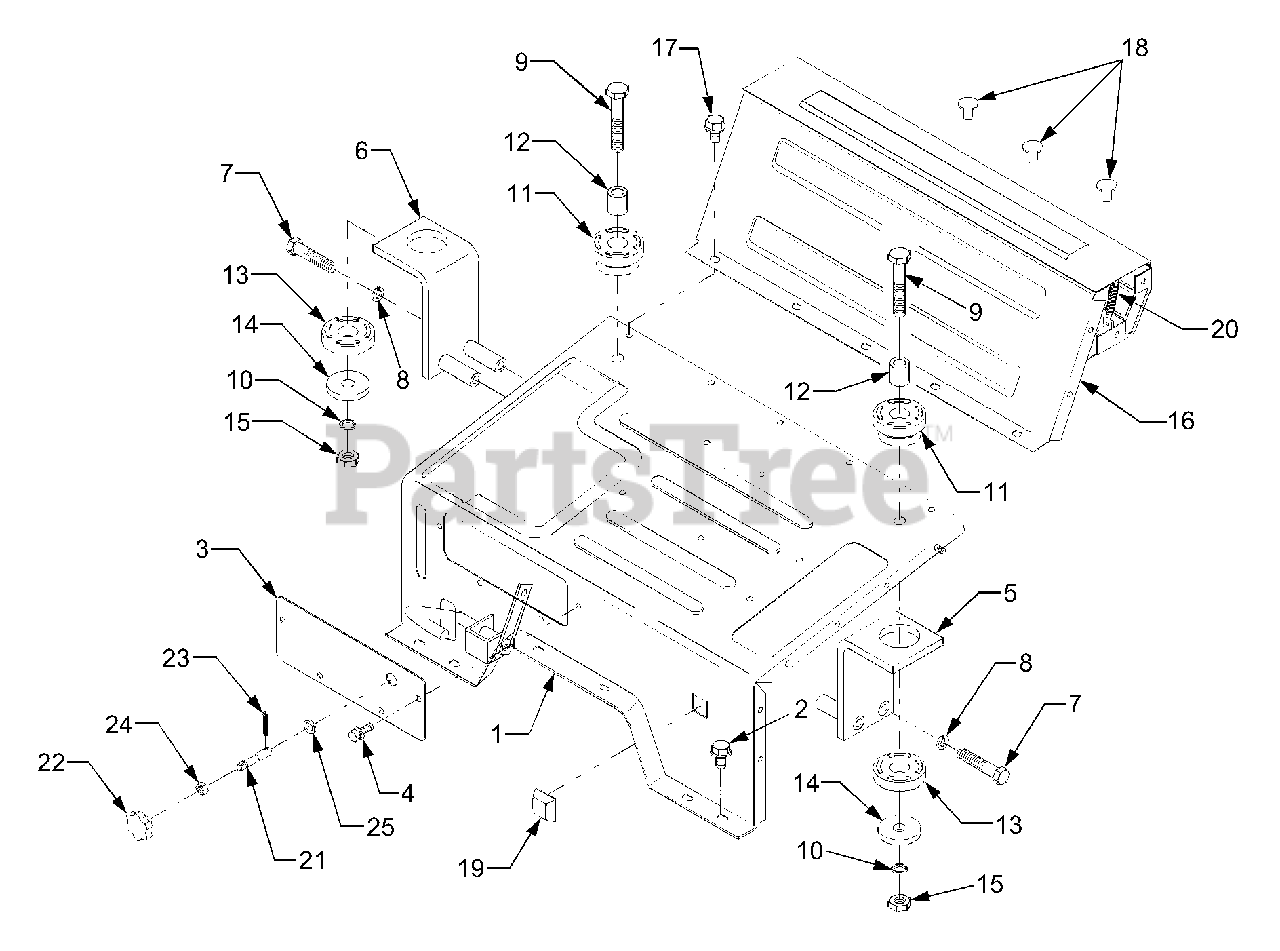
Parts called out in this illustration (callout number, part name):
1	Seat Floor Ass'y
5	Support, Seat Floor (LH)
6	Support, Seat Floor (RH)
8	Washer, Spring
10	Washer, Spring
11	Rubber, Cabin Cushion (A)
12	Collar, Cabin Cushion (A)
13	Rubber, Cabin Cushion (B)
16	Seat Rear Plate Ass'y
19	Cap, Bi-Speed
21	Rod, Hydraulic Control
